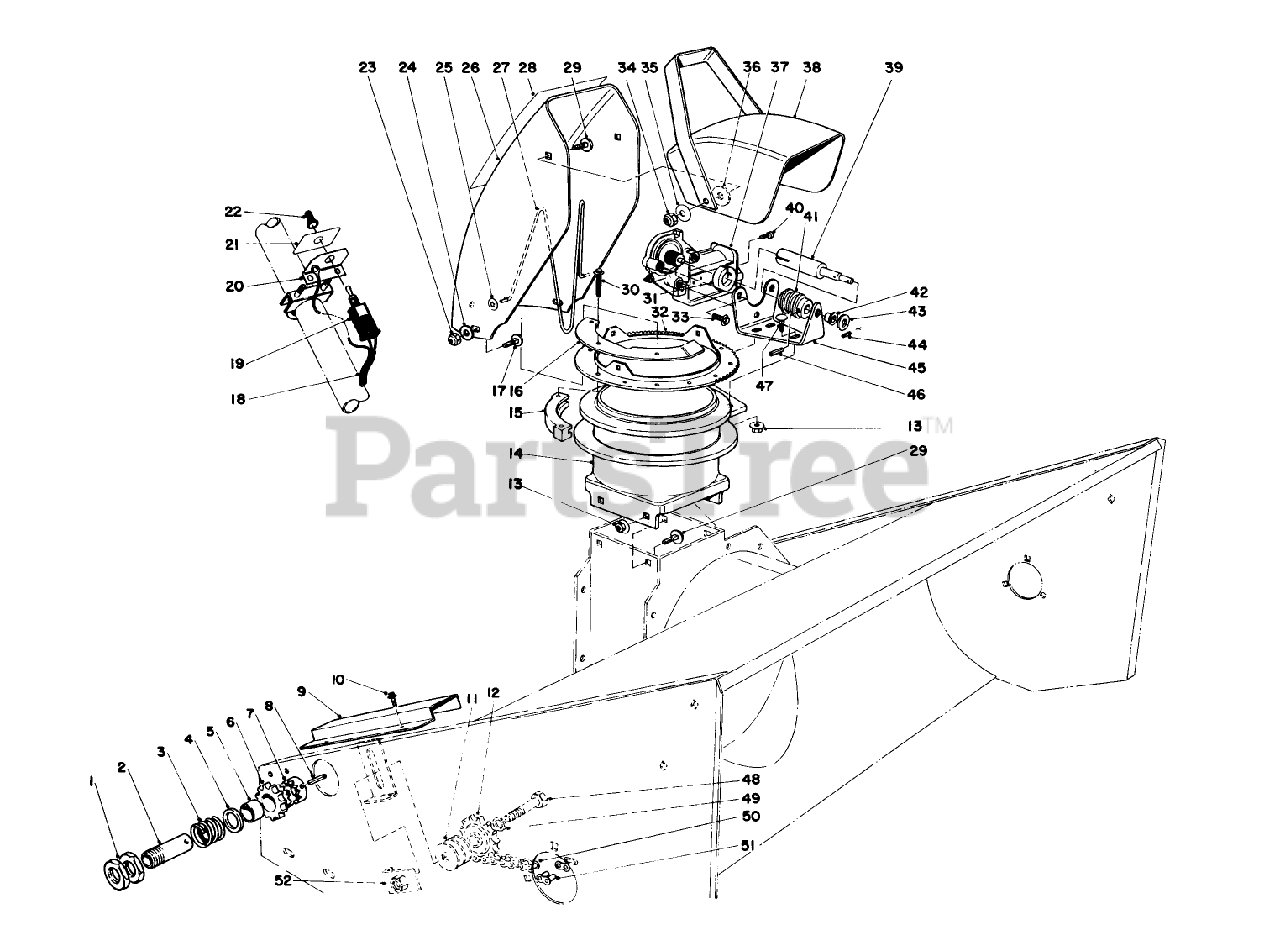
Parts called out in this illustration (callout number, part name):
1	THIN NUT
2	Clutch Sleeve
3	Spring Compression
6	Clutch Sprocket
7	Clutch Collar
8	PIN-ROLL
9	Chain Cover
10	SCREW-HWHTF
11	WASHER-FLAT
12	IDLER SPRKT (60016)
13	NUT-HHF, WHIZ
14	Chute Transition
15	RETAINER-CHUTE
16	Stop-Chute Rotator
17	SCREW-CARR
18	WIRE HARNESS
19	Toggle Switch
20	Toggle Switch Mount
21	DECAL
22	BOOT-SWITCH
23	NUT-LOCK, NI
24	WASHER-PLAIN
25	NUT-PUSH
26	Upper Chute
27	WIRE-CHUTE
28	Decal-Warning
29	SCREW-CARR
30	SCREW-SPECIAL
31	SPLIT COLLAR
32	RING - CHUTE SWIVEL
33	SCREW-HHF
34	NUT-LOCK, CONE
35	WASHER-BELLEVILLE
36	WASHER-RUBBER
37	ELEC GEAR MOTOR
38	Deflector
39	WORM GEAR SHAFT
40	SCREW-HSH
41	GEAR-WORM, CHUTE
42	FLANGE BSHG #FF-310-3
43	WASHER-FLAT
44	3/32 X 9/16 ROLL PIN
45	Motor Mount
46	PIN-SPRING
47	BOLT-CARR
48	SCREW-HH
49	WASHER-LOCK
50	ROLLER CHAIN (60023)
51	LINK-CHAIN
52	NUT PLATE WA (60095)
